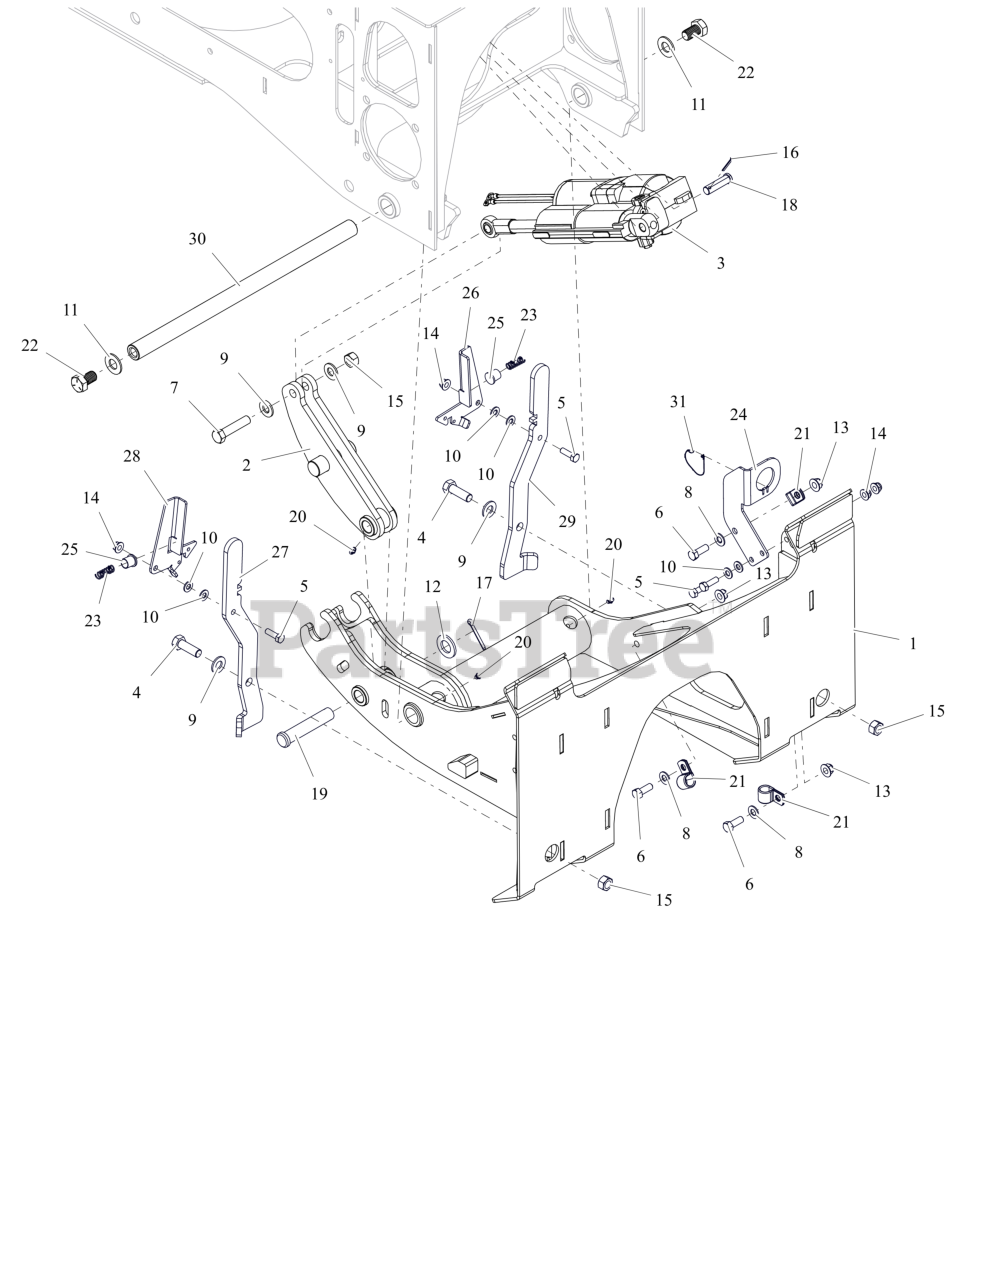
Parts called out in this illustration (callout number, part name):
1	WLDMT, LIFT FRAME - W/ZERK AND DECAL
2	WLDMT, LINK LIFT - W/ZERK
3	ACTUATOR- LINEAR PARKER EHA
4	BLT,HEX .50-13X1.50 G5 ZCC
5	BLT,HEX .31-18X1.00 G5 ZCC
6	BLT,HEX .38-16X1.00 G5 ZCC
7	BLT, HEX .50-13X2.25 G5 ZCC
8	WSHR,FLT .406X.812X.065 ZCC
9	WSHR,FLT .531X1.062X.095 ZCC
10	WSHR,FLT .344X.688X.065 ZCC
11	WSHRFLT 5/8SAE CARBHARD FBP
12	WSHR, FLT .812X1.469X.134 ZCC
13	NUT,NYL-FLG .38-16 GF ZCC
14	NUT,LK-NYL-FLG .31-18 G5ZC120
15	NUT,LK-CTR .50-13 GA ZCC
16	PIN,CTR.12X1.25EXTPRSQCT ZC120
17	PIN, CTR .18X1.50 EXTPRSQCT ZC120
18	PIN- CLEVIS .50 X 1.75"
19	PIN- CLEVIS
20	FITTING, LUBE .25-28X.256 ZC120
21	CLAMP, HARNESS - "P" (5/8" ID)
22	BOLT- HEX 5/8-11 X 1" GR5
23	SPRG- COMPRESSION
24	PLATE- BRKT CONNECTOR
25	CAP- DUST
26	LATCH- LEFT COUPLER
27	HANDLE- RIGHT COUPLER
28	LATCH- RIGHT COUPLER
29	HANDLE- LEFT COUPLER
30	PIN- PIVOT
31	WIRE, CAP LANYARD
